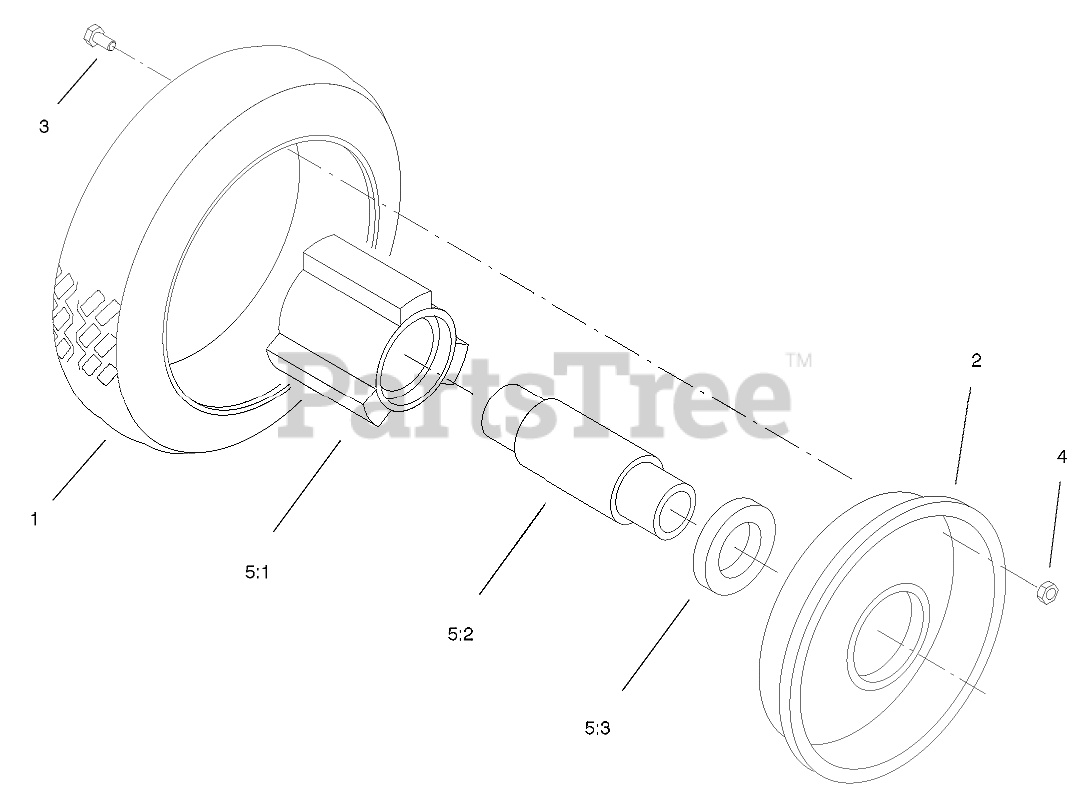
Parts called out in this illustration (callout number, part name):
2	PLATE-WHEEL, HALF
3	SCREW-HH
4	NUT-LOCK, NI
5	Hub and Bearing ASM
5:1	HUB-BEARING
5:2	SPACER-BEARING
5:3	BEARING-WHEEL
